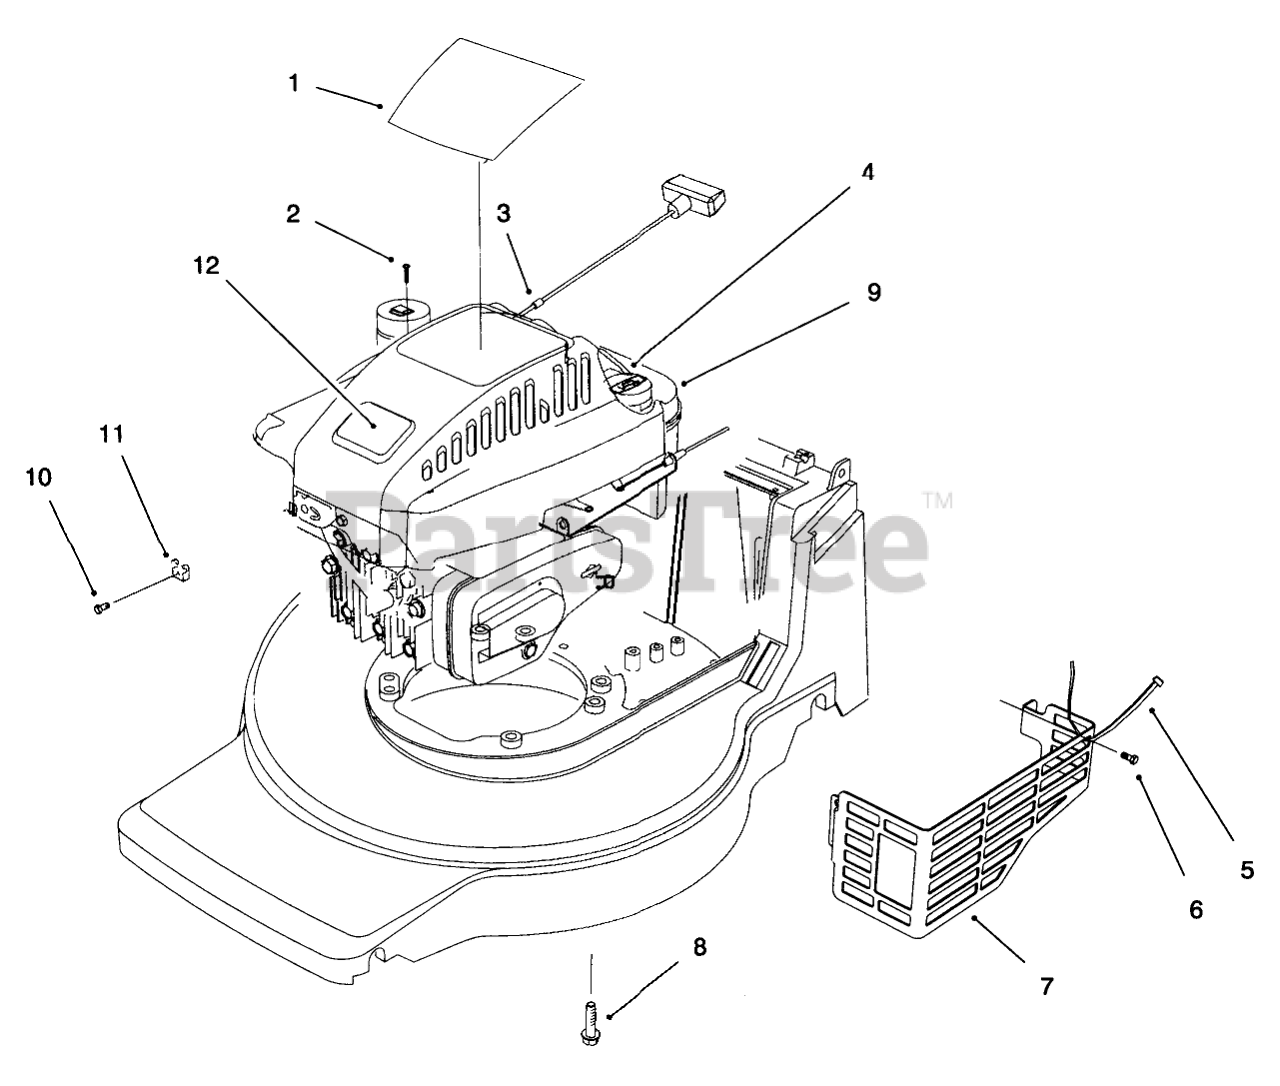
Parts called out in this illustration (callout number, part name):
1	DECAL - RECOIL
2	SCREW-PPH
3	STOP-ROPE
4	SHROUD-ENGINE
5	TIE-CABLE
6	SCREW-HWH
7	SHIELD-MUFFLER
8	SCREW-HWH
9	Engine-B & S Quantum
10	SCREW-CLAMP
11	CLAMP-CASING
12	PLATE-LOGO
